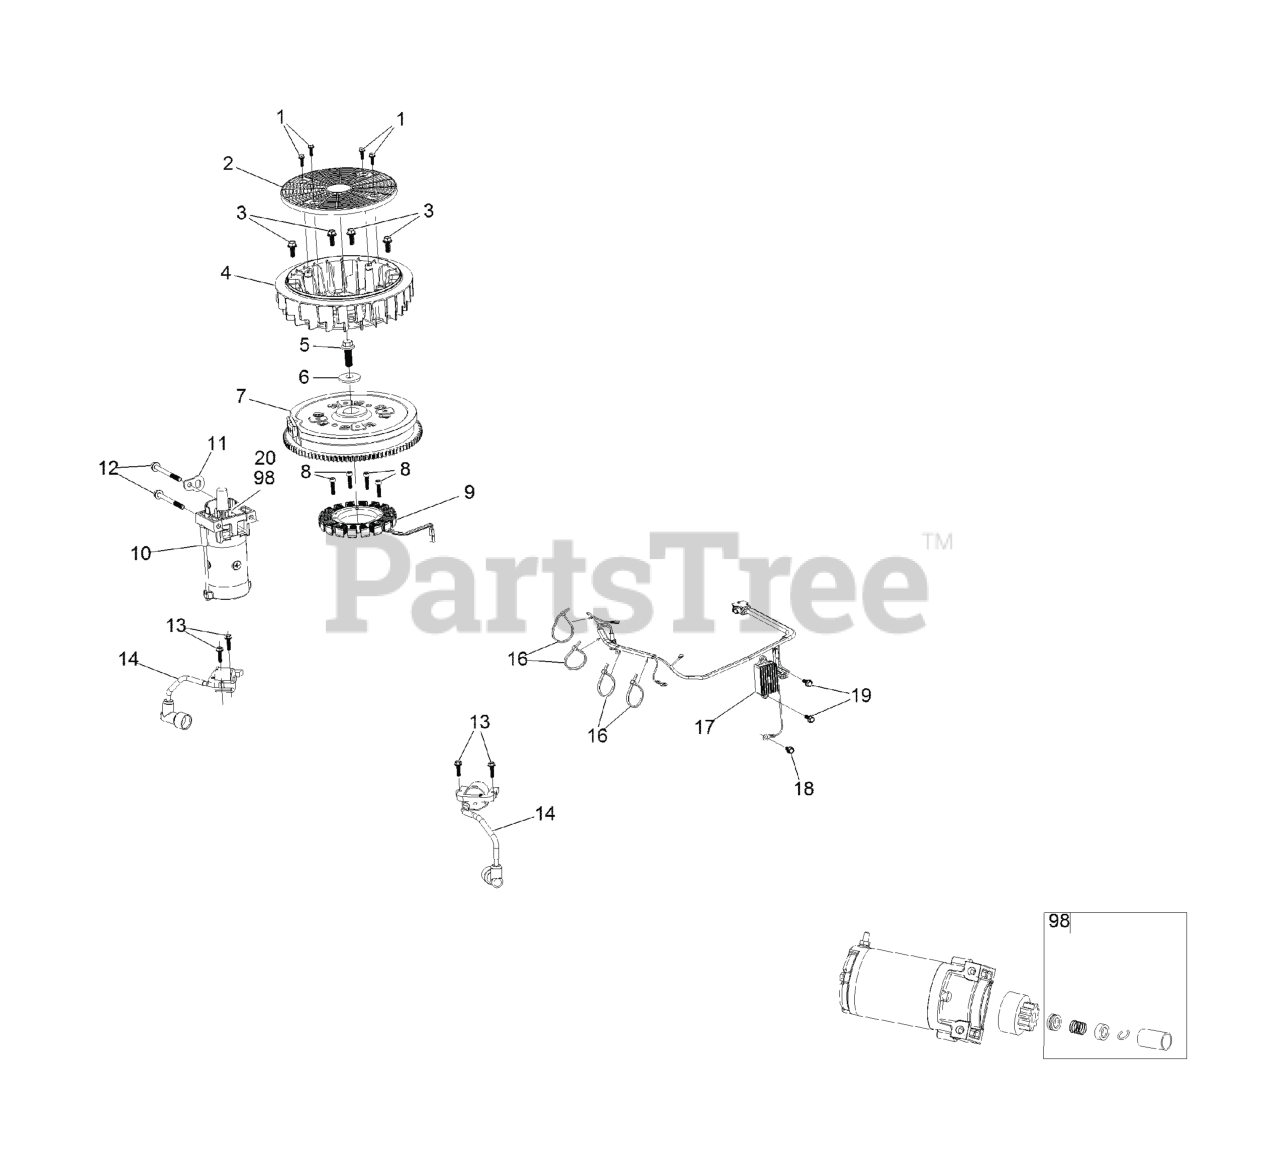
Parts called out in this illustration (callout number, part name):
1	SCREW-HWH
2	SCREEN-ROTATING
3	SCREW-HWH
4	FAN-COOLING
5	SCREW-HWH
6	WASHER-FLAT
7	FLYWHEEL
8	SCREW-HSH
9	ALTERNATOR
10	MOTOR-STARTER
11	BRACKET-LIFT
12	SCREW-HHF
13	BOLT-FLANGE
14	IGNITION COIL ASM
16	TIE-ZIP
17	REGULATOR-VOLTAGE, W/HARNESS
18	SCREW-HHF
19	SCREW-HHF
20	PINION-STARTER
98	STARTER REPAIR KIT
